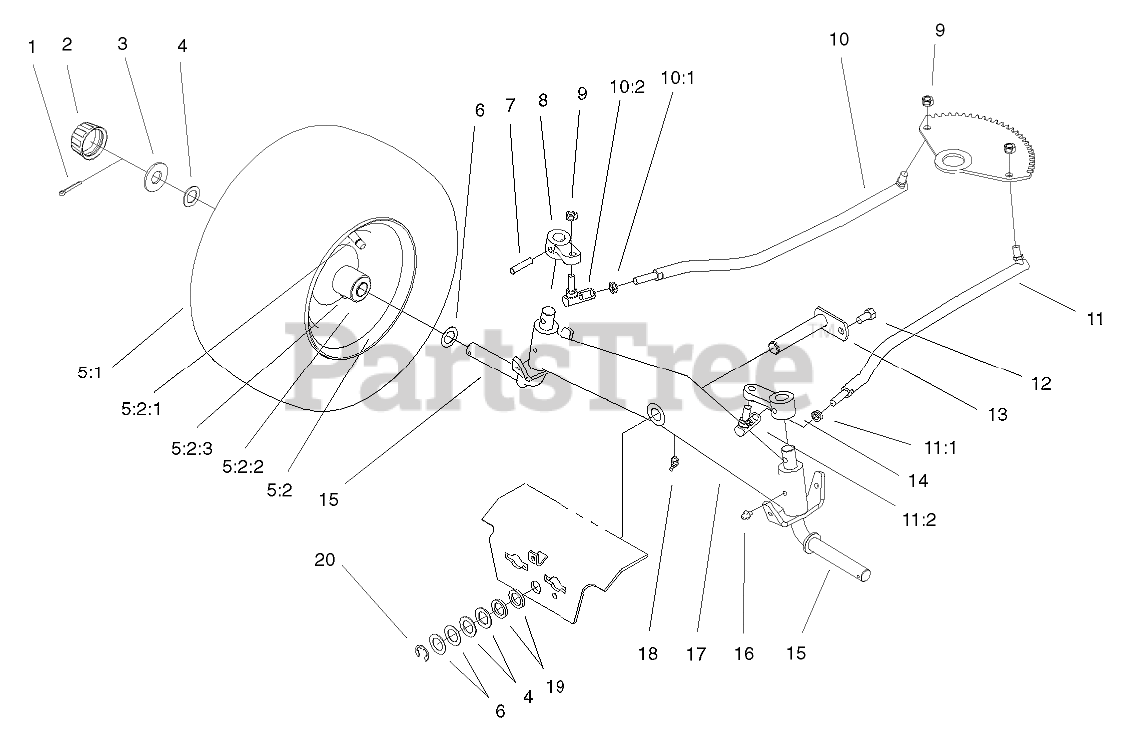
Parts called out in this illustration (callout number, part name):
1	PIN-COTTER
2	CAP-HUB
3	WASHER-PLAIN
4	WASHER
5:2	Wheel ASM
5:2:1	VALVE
5:2:2	BEARING-WHEEL
5:2:3	ZERK-GREASE
6	WASHER-SHIM
8	Arm-Front Spindle
10	LINKAGE-STEERING, RH
10:1	NUT-JAM
10:2	BALL-JOINT
11	LINKAGE-STEERING, LH
11:1	NUT-JAM
11:2	BALL-JOINT
12	SCREW-HWH, TAPTITE
13	PIN-AXLE
14	Arm-Front Spindle
15	SPINDLE
16	FITTING-GREASE
17	AXLE-FRONT
18	FITTING-LUBE, 45 DEG
19	Washer
20	E-RING
